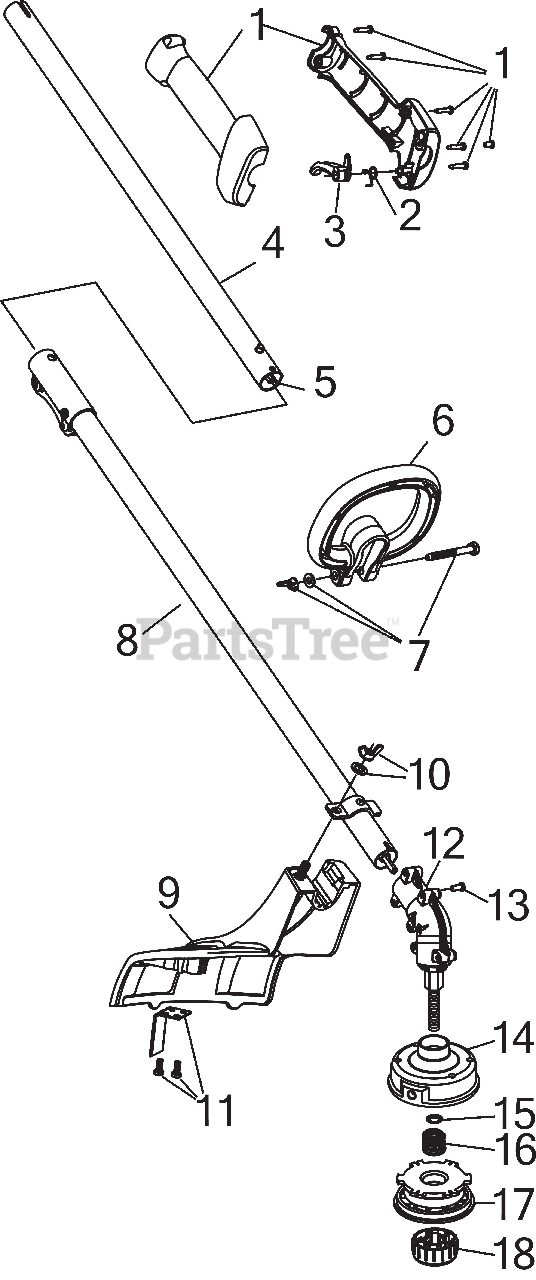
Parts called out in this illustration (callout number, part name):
1	THROTTLE GRIP ASSEMBLY
2	SPRING, TRIGGER
3	THROTTLE TRIGGER
4	UPPER BOOM ASSEMBLY COM
5	UPPER SHFT
6	HANDLE
7	HANDLE HWD
8	LOWER BOOM ASSEMBLY
9	GUARD & BLADE ASSEMBLY
10	BLADE GUARD MOUNTING HARDWARE
11	BLADE ASSEMBLY W/HDW
12	GEARBOX ASSEMBLY
13	SCREW 8-32X.437
14	REEL:OTR W/RET
15	RETAINER .625 OD 2
16	SPRING-SPOOL
17	REEL-INNER SPOOL
18	BUMP HEAD KNOB ASSEMBLY
